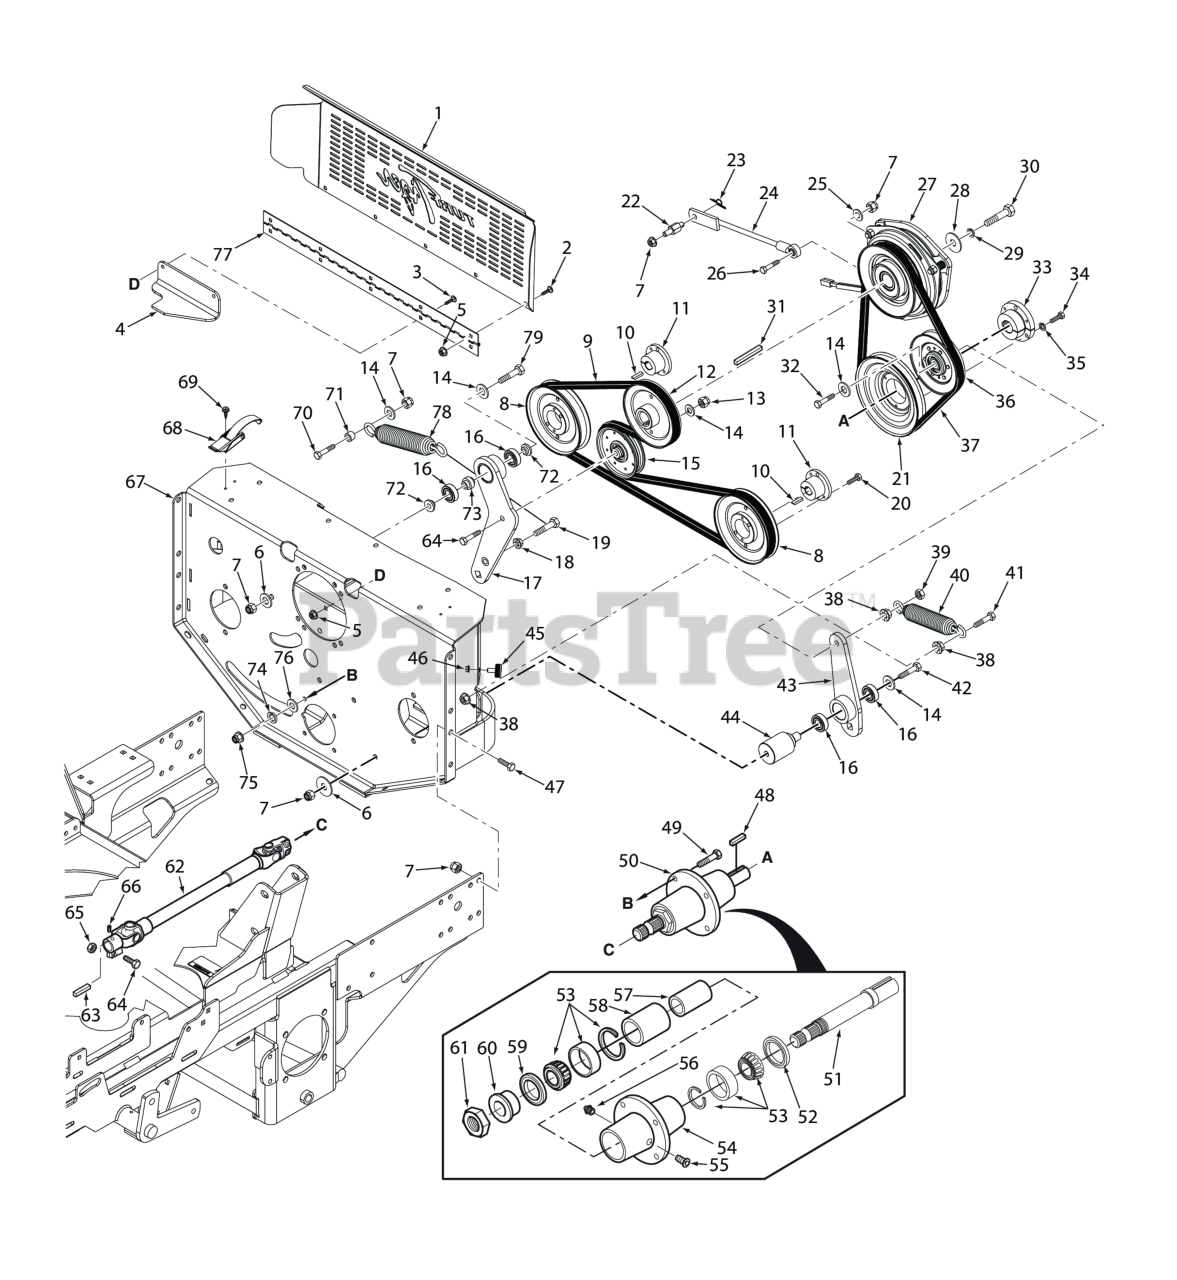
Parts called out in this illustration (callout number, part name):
1	Cover, Rear
2	Bolt, Carriage 1/4-20 x 1/2"
3	Serr. Fl. Hex Head CPSCR, 1/4-20 x 3/4"
4	Bracket, Idler Stop
5	NUT, 1/4-20 SERRATED FLANGE HEX HEAD
6	Flatwasher, 3/8-.406 x 1-1-1/2 x 7 Gauge
7	HEX NUT, ELASTIC STOP LOCK, 3/8-16
8	Pulley, 5.75 O.D. (Gasoline Engines)
9	Belt, STTII Pump Drive (Gasoline Engines)
10	Key, 5mm x 5mm x 30mm
11	Tapered Hub, 17mm Bore
12	Pulley, 5.67 O.D. (Kawasaki & Kohler Only)
13	Bolt, Hex Head 3/8-16 x 1" Ser. Flg.
14	Flatwasher, 3/8 (.391 x .938 x .105 HD) Grade 8
15	Pulley, Idler 4� Dia.
16	BEARINGS, BALL, NEUTRAL RETURN
17	Idler Arm Assy.
18	Nut, Hex Serrated Flange 1/2-13
19	Bolt, Hex Head 1/2-13 x 2� Grd 8
20	Bolt, Hex Head 1/4-20 x 1" Grade 8 Black
21	Pulley, 6.70" O.D. Tapered Bore
22	STUD, ANTI-ROTATION
23	Pin, Rue Cotter 3/8" Diameter
24	Rod Assembly, Clutch Anti-Rotation
25	Flatwasher, 3/8-.438 x 1.00 x .083
26	Bolt, Hex Head 3/8-16 x 1-1/4", Kawasaki FX / FT & FT-EFI
27	Electric Clutch w/Tag - GT-3.5 (FX850)
28	Flatwasher, 7/16-.469 x 1.75 x .25 (48, 52)
29	Lockwasher, 7/16� Spring
30	Bolt, Hex Head 7/16-20 x 2-1/2" (Kohler)
31	Key, 1/4 x 1/4 x 3-1/4�
32	Bolt, Hex Head 3/8-16 x 2-1/2" 1.5 Thread Grd.8
33	Tapered Hub, 1.00 Bore
34	BOLT, HEX HEAD, 1/4-20 X 1-3/8(FULL THREAD)
35	Lockwasher, 1/4� Spring
36	IDLER PULLEY, "V" GROOVE
37	Belt, Pump Drive - Kubota
38	NUT, 3/8-16 SERRATED FLANGE HEX HEAD
39	Bolt, Hex Head 3/8-16 x 1" Ser. Flg.
40	Spring, PTO (Gasoline Engines)
41	Bolt, Hex Head 3/8-16 x 1-1/2" Grade 8 Black
42	Bolt, Hex Head 3/8-16 x 4-1/2" Grade 8 Black
43	Idler Arm Weldment, PTO Drive
44	Pivot, Idler - PTO
45	Bumper, Rubber 5/16-18 x 5/8"
46	Nut, Serrated Flange 5/16-18 (Right Front Engine Mounting, Briggs and Kohler Only)
47	Bolt, Hex Head, 3/8-16 x 1 Gr. 5
48	KEY 1/4 X 1/4 X 1 1/2"(FOR 1" CRANKSHAFT
49	Bolt, Hex Head 5/16-18 x 1-3/4" Grade 8
50	Spindle Assembly, Deck Drive
51	Shaft, Deck Drive
52	SEAL, 2.00 O.D. X 1.50 BORE
53	Tapered Bearing Set (Two Bearings W/Race)
54	Housing, Spindle
55	RELIEF FITTING, TAPERED BEARING SPINDLE
56	GREASE FITTING, STR. 1/4-28 SELF TAP.
57	SLEEVE, CUTTER SPINDLE
58	Spacer, Outside, Cutter Spindle
59	Seal, 2.00" O.D. x 1.625" Bore
60	SPINDLE BUSHING, BOTTOM
61	Nut , Spec ial 1 -1/ 1 6 - 1 8
62	Driveshaft (Air Cooled Engine)
63	Key, 1/4" x 1/4" x 1" Clutch Mtg.
64	Bolt, Hex Head 3/8-16 x 1-3/4" (Kohler EFI)
65	Bolt, Hex Head 3/8-16 x 1" Ser. Flg.
66	Set Screw, 3/8-16 x 1/2" Internal Hex
67	Pump Mounting Plate Weldment (Gasoline)
68	LATCH, HOOD
69	Screw, #10-32 x .563 Shakeproof
70	Bolt, Hex Head 3/8-16 x 1-1/2" B&S 32BV
71	Spacer, Spring Anchor
72	Spacer, Controls
73	Spacer, Bearing
74	Lockwasher, 5/16 (.317 x .586 x .078) Helical Spring
75	Lock Nut, 5/16-18 Elastic Stop Grade 8
76	Flatwasher, 5/16-.375 x .875 x .083 (35BV & 37BV-EFI)
77	Hinge, Rear Belt Guard
78	Spring, PTO (Gasoline Engines)
79	Capscrew, Hex Head 3/8-16 x 2.75"
